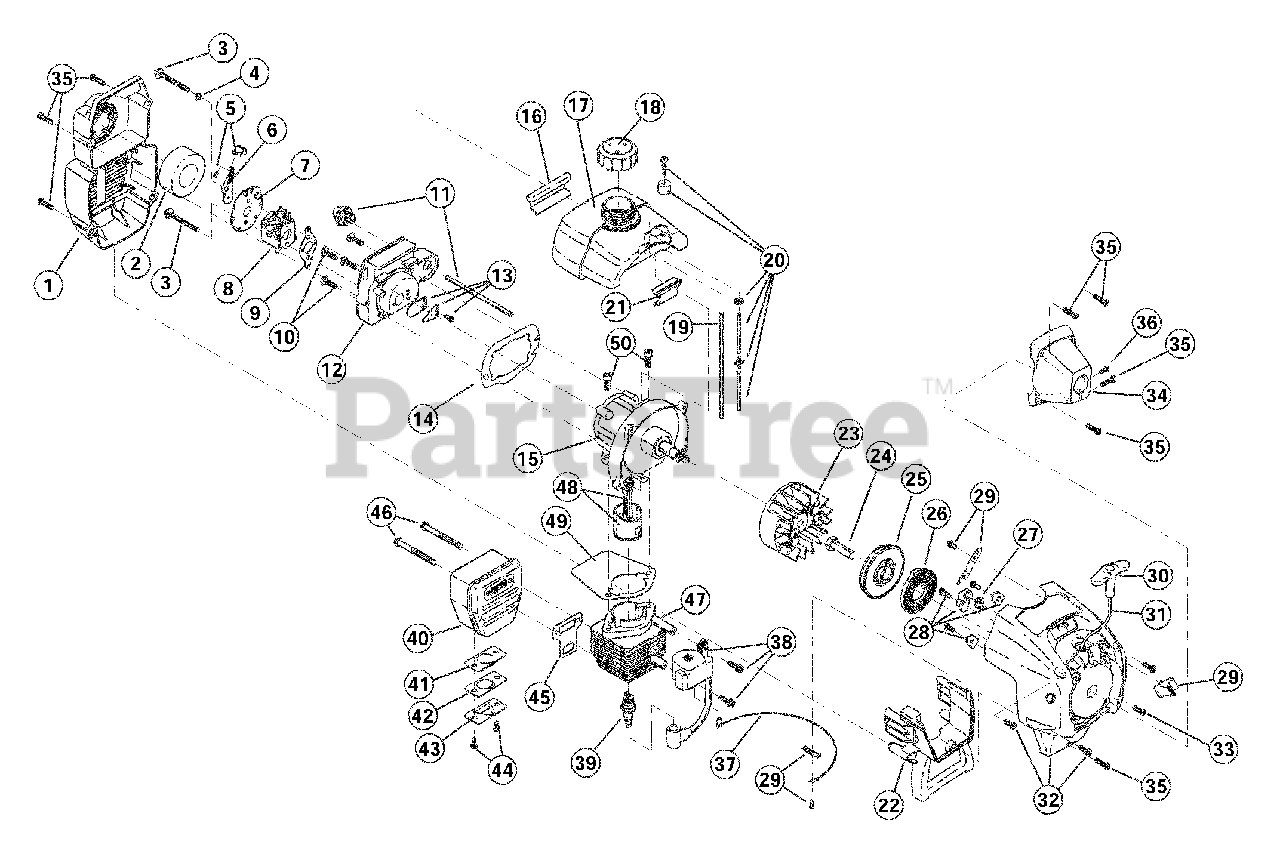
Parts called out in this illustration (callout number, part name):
1	Air Cleaner/Muffler Cover Assembly
2	Air Cleaner Filter
3	Carburetor Mounting Screw Assembly
4	Wavey Washer
5	Choke Knob and Screw
6	Choke Lever Assembly
7	Choke Lever and Plate
8	Carburetor Assembly
9	Carburetor Gasket
10	Carb Mount Screw
11	Primer and Hose Assembly
12	Carb Mount Assembly
13	Reed Assembly
14	Carburetor Mount Gasket
15	Crank Case Service Assembly
16	Rear Mounting Pad
17	Fuel Tank Assembly
18	Fuel Cap Assembly
19	Fuel Return Line
20	Fuel Line Assembly
21	Front Mounting Pad
22	Shroud Extension and Stand
23	Flywheel Assembly
25	Recoil Pulley Assembly
26	Recoil Spring
27	Rope Guide
28	Pulley Retainer Assembly
29	Switch Assembly
30	Pull Handle
32	Starter Housing Assembly
33	Housing Screw
34	Clutch Cover Assembly
36	Anti-Rotation Screw
37	Wire Lead
38	Module Assembly
39	Spark Plug
40	Muffler Assembly
41	Spark Arrestor Screen
42	Exhaust Hood Diverter
43	Exhaust Hood
44	Screw
45	Exhaust Gasket
46	Muffler Mounting Bolt Assembly
47	Cylinder Assembly
48	Piston and Rod Assembly
49	Cylinder Gasket
50	Cylinder Bolt
